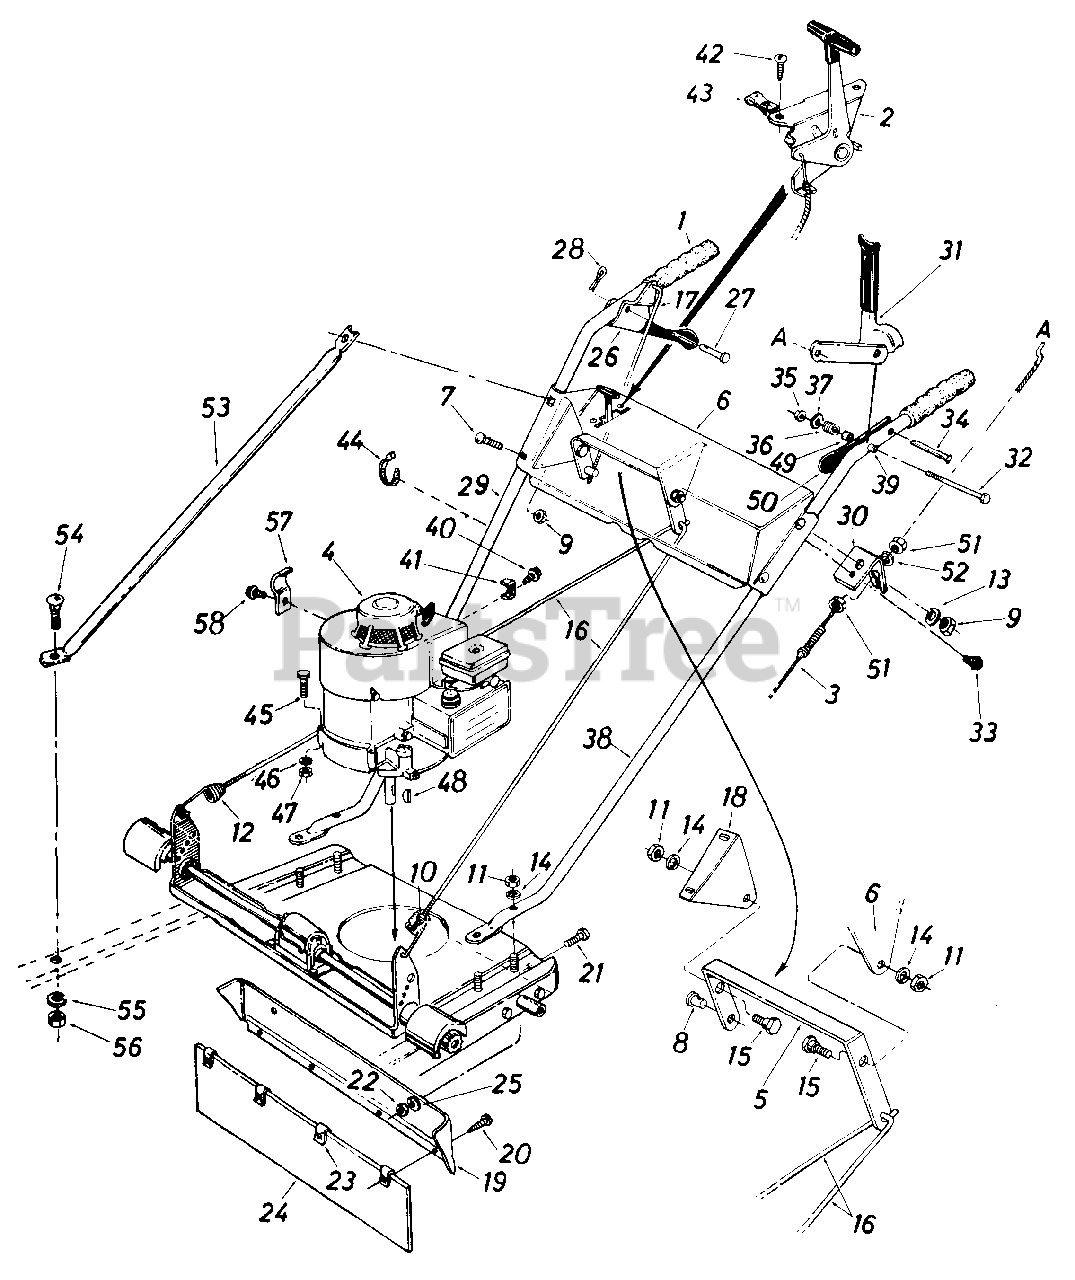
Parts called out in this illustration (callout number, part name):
2	CONTROL-THROTTLE ASSY-COMP
3	CABLE-CLUTCH 56.0
5	BRACKET-LINKAGE
6	PANEL ASSY-HANDLE
7	BOLT-CARRIAGE 5/16-18 X 1.75
8	FERRULE-ADJ
9	NUT-HEX 5/16-18
10	NUT-INS LOCK 1/4-20
11	NUT-HEX 3/8-16
12	SPRING-EXTENSION
13	WASHER-LOCK-5/16
14	WASHER-LOCK-3/8
15	SCREW-SHLD .500 DIA X .295
16	ROD-LOCKOUT
18	BRACKET
19	ADAPTER-DRAG SHIELD
20	SCREW-HEX WASH HD TAP
21	SCREW-HEX 1/4-28 X .62
22	NUT-HEX 1/4-28
23	NUT-SPEED-U TYPE
24	SHIELD-DRAG
25	LOCK WASHER 1/4 DIA
26	GRIP ASSY-CLUTCH
27	PIN-CLEVIS 3/8 X 1.620
28	PIN-INTERN COT-5/16 DIA
29	HANDLE-RH
30	BRACKET-CLUTCH CABLE
31	GRIP ASSY-BLADE CL
32	SCREW-HEX 1/4-20 X 2.25
33	SCREW-HEX WASH SF TAPP
34	PIN-LOCKING
35	NUT-HEX LOCK 1/4 X 20
36	SPRING-COMPRESSION
37	WASHER-INTERN L 1/4
38	HANDLE-LH
39	SPACER
40	SCREW-HEX B-TAP #10 X .38
41	CLAMP-CASING
42	SCREW-HEX AB-TAP #10 X .50
43	NUT-HEX JAM
44	TIE-CABLE
45	SCREW-HEX 5/16-24 X 1.25
46	WASHER-LOCK-5/16
47	NUT-5/16-24
48	KEY-HI-PRO #6-5/32 X 5/8 DIA
50	SPRING-LOCKOUT
51	NUT-HEX JAM 5/16-24
52	WASHER-LOCK-5/16
53	STRUT-HI WHL
54	BOLT-CARRIAGE 5/16-18 X .62
55	WASHER-LOCK-5/16
56	NUT-HEX 5/16-18
57	CLAMP-CASING
58	SCREW-HEX DRILLING #10 X .50
